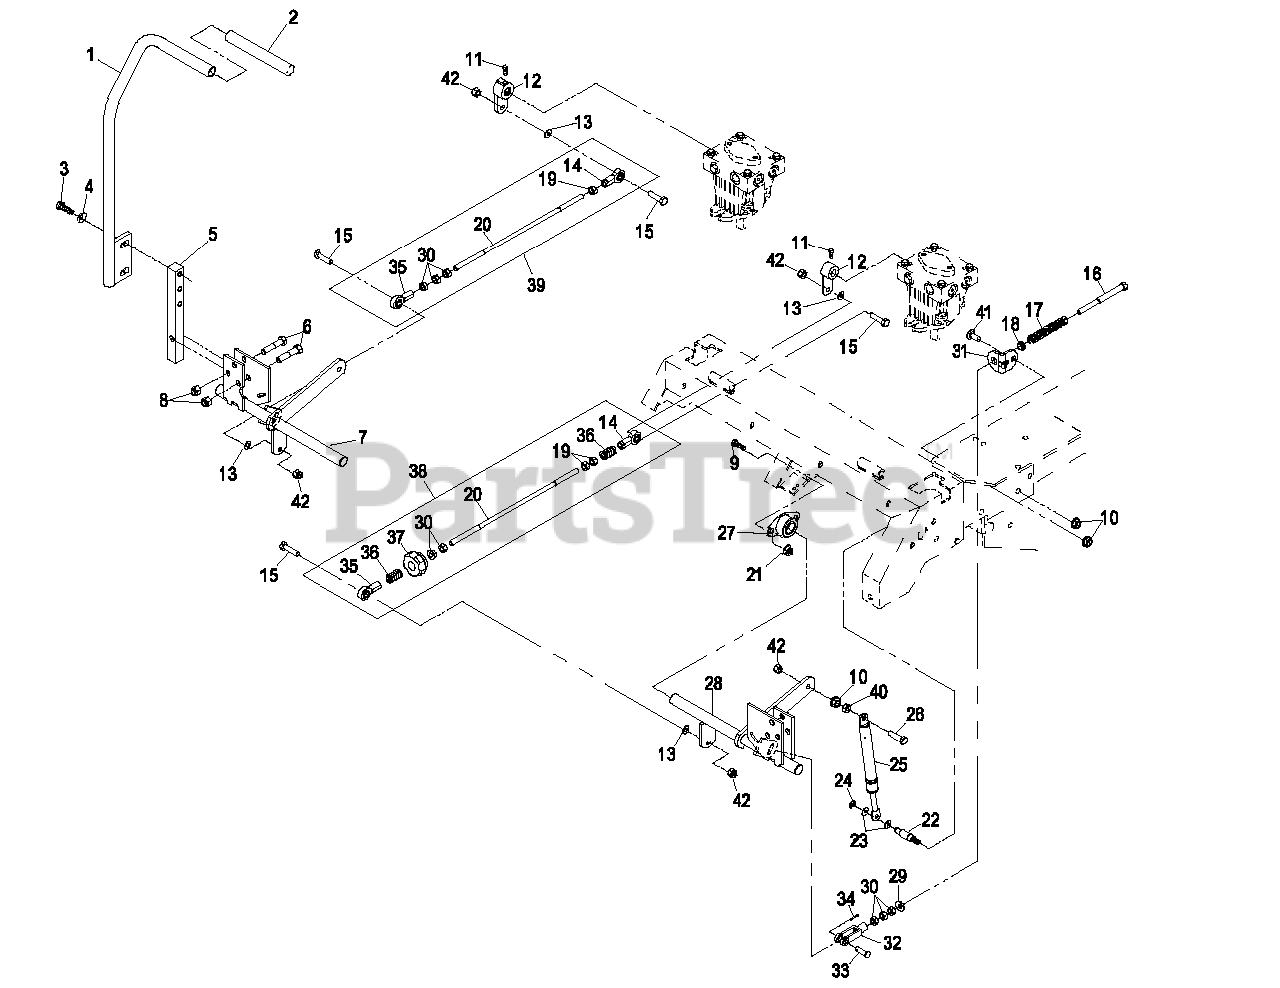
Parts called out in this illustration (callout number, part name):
1	RH LEVER ASM
2	GRIP-CONTROL, MOTION
3	SCREW-HH
4	WASHER-BELLEVILLE
5	ARM-SHAFT, CONTROL
6	SCREW-HH
8	NUT-LOCK, NI
9	SCREW-HH
11	SCREW-SET
12	ARM-CONTROL
13	WASHER-FLAT
14	BALLJOINT-LH
15	SCREW-HH
16	BOLT-RETURN, NEUTRAL
17	SPRING-RETURN, NEUTRAL
18	BUSHING-NYLON, FLANGED
20	LINK-ROD, TRACKING
21	NUT-HHF, WHIZ
22	PIN-DAMPER
23	WASHER-PLAIN
24	RING-RETAINING, EXT
25	DAMPER-CONTROL, MOTION
26	SCREW-HH
27	BEARING-FLANGE, SIDE
28	CONTROL-MOTION, LH
29	WASHER-FLAT
30	NUT-HEX
31	TAB-ADJUSTMENT
32	YOKE-ADJUSTABLE
33	PIN-CLEVIS
34	PIN-COTTER
35	BALLJOINT-RH
36	SPRING-COMPRESSION
37	KNOB-TRACKING
38	TRACKING ROD ASM
39	TRACKING ASM
40	NUT-HEX
41	SCREW-CARR
42	NUT-LOCK, NI
